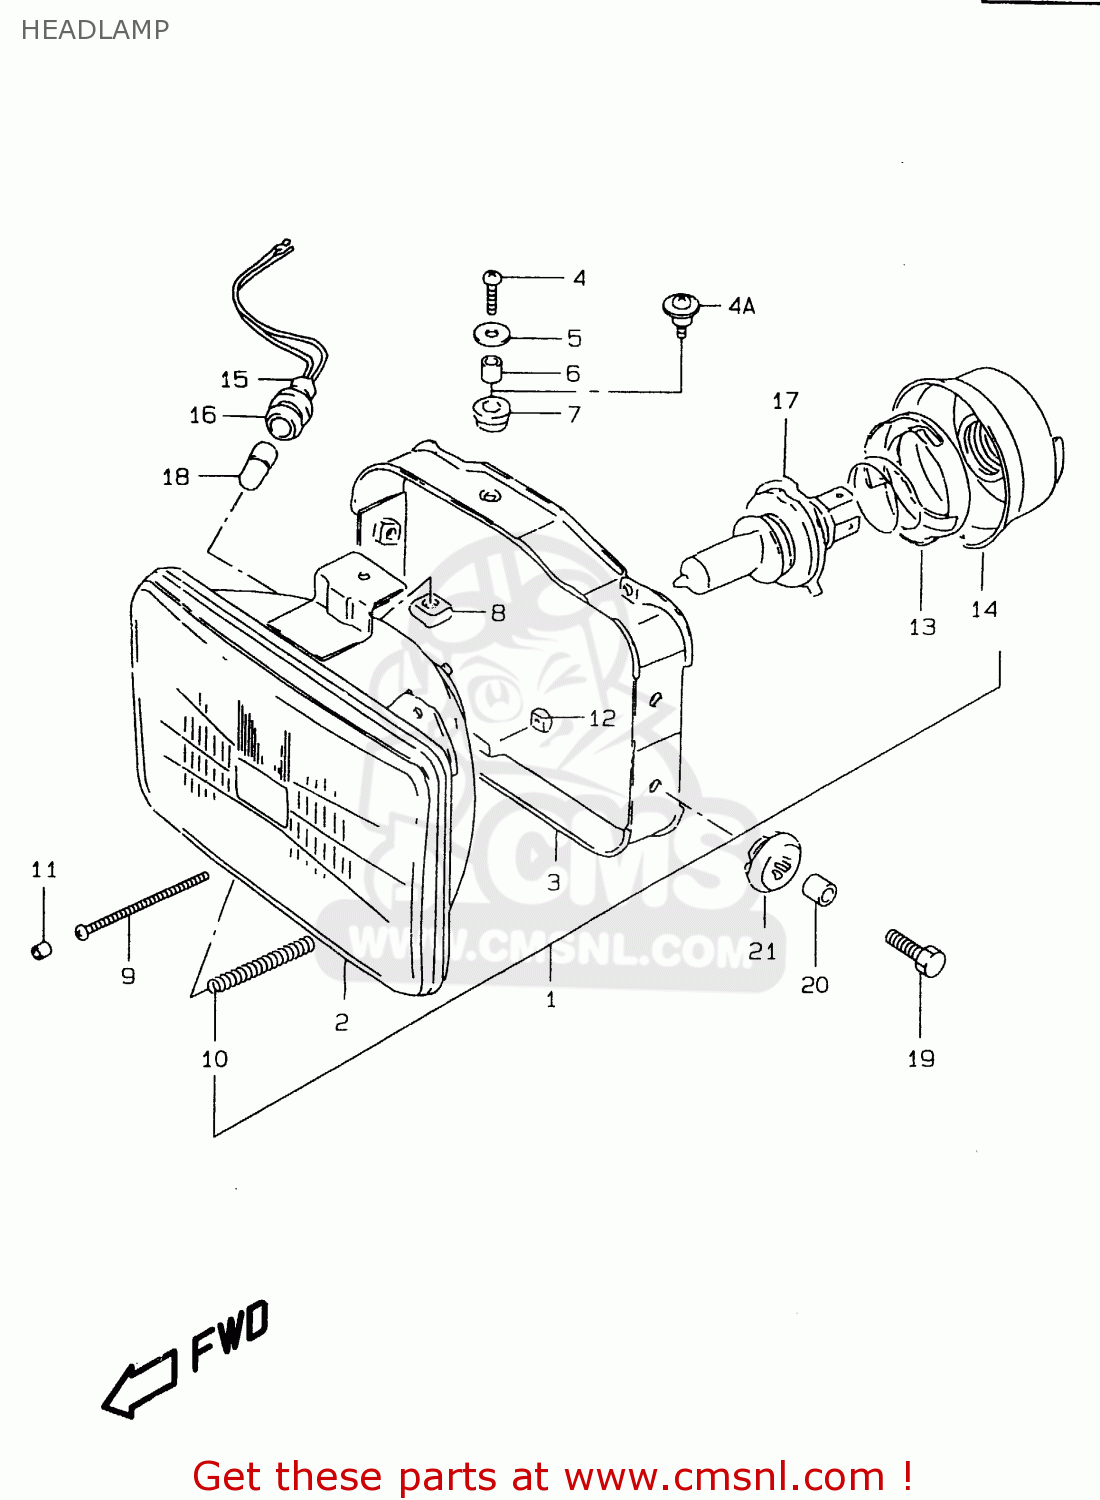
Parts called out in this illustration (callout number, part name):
1	HEADLAMP ASSY
2	LAMP UNIT
3	HOUSING
4	SCREW
4A	SCREW,MOUNTING
5	WASHER(5.5X18X1)
6	SPACER
7	CUSHION
8	NUT
9	SCREW
10	SPRING
11	CAP,SCREW
12	NUT
13	HOLDER,BULB
14	COVER,SOCKET
15	SOCKET
16	JOINT,RUBBER
17	BULB(12V60/55W,H4)
18	BULB(12V4W)
19	BOLT 6X20
20	SPACER(6.5X9X9)
21	CUSHION
